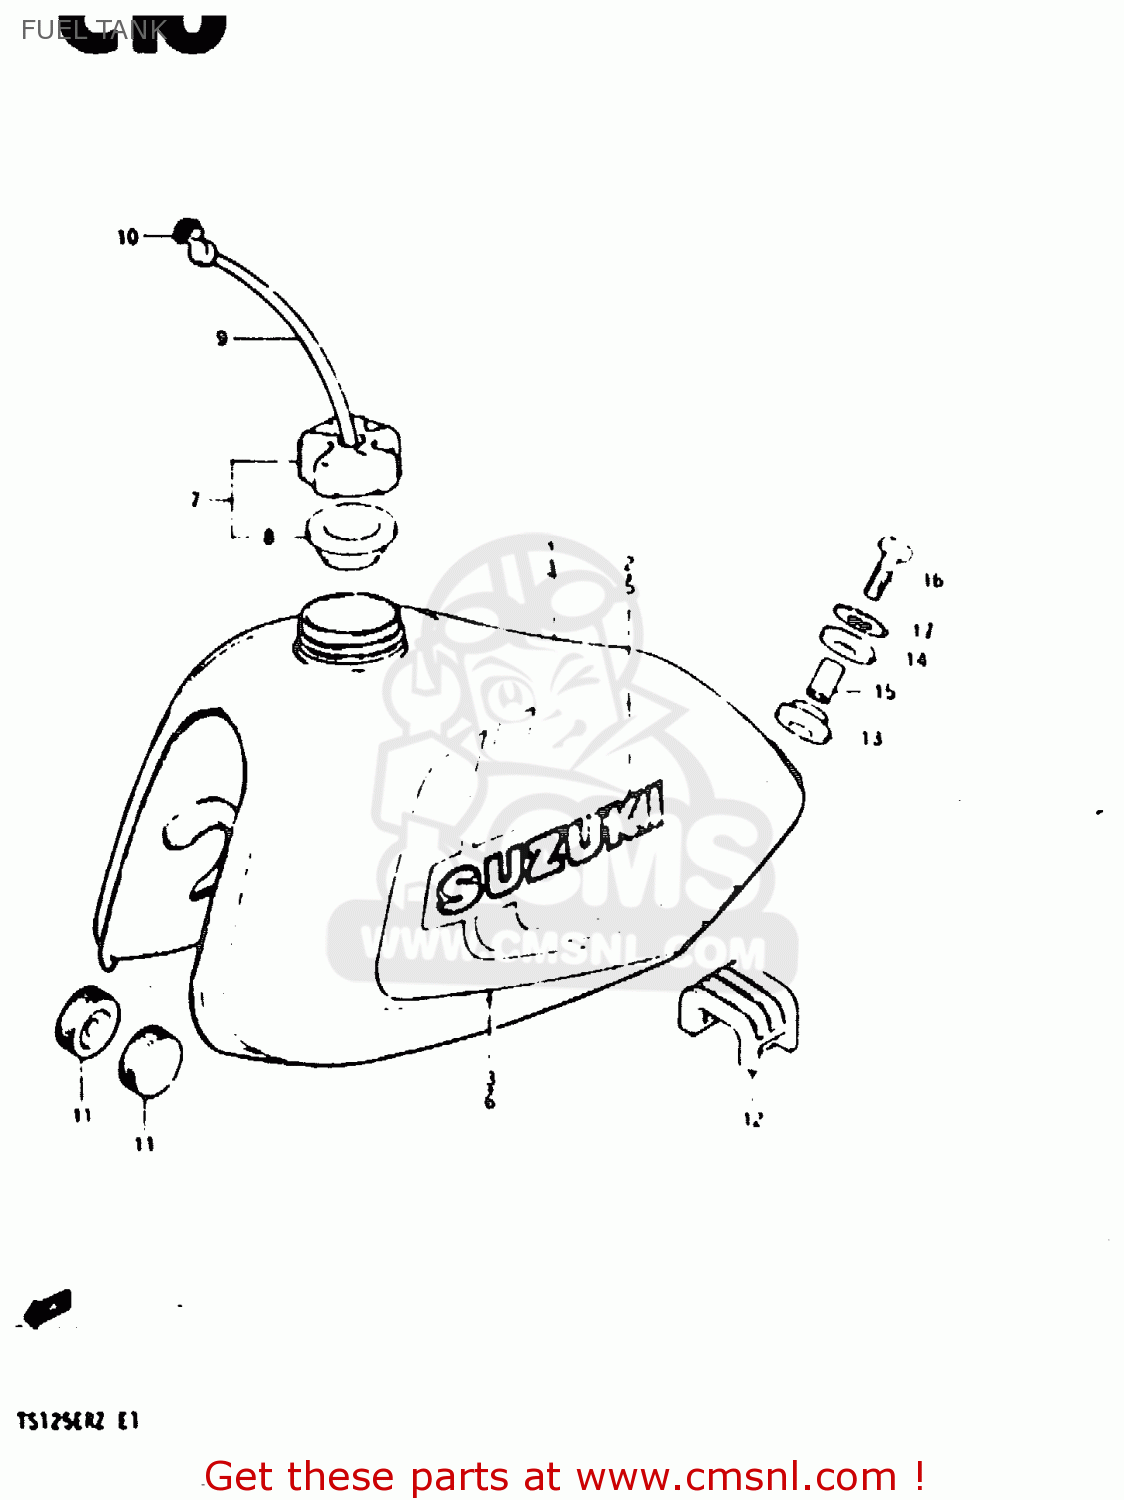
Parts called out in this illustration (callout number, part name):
1	TANK, FUEL (YELLOW)
2	EMBLEM (BLUE)
3	TAPE SET
4	TANK, FUEL (RED)
5	EMBLEM(WHITE)
6	TAPE SET,FUEL TANK
7	CAP SET,FUEL TANK
8	GASKET (NAS)
9	HOSE
10	CLAMP,FUEL TANK BREATHER HOSE
11	CUSHION
12	CUSHION,FUEL TANK UPR
13	CUSHION,FUEL TANK RR NO.1
14	CUSHION,FUEL TANK RR NO.2
15	SPACER(8.5X12X19)
16	BOLT (8X30)
17	WASHER (8.5X29X1.6)
